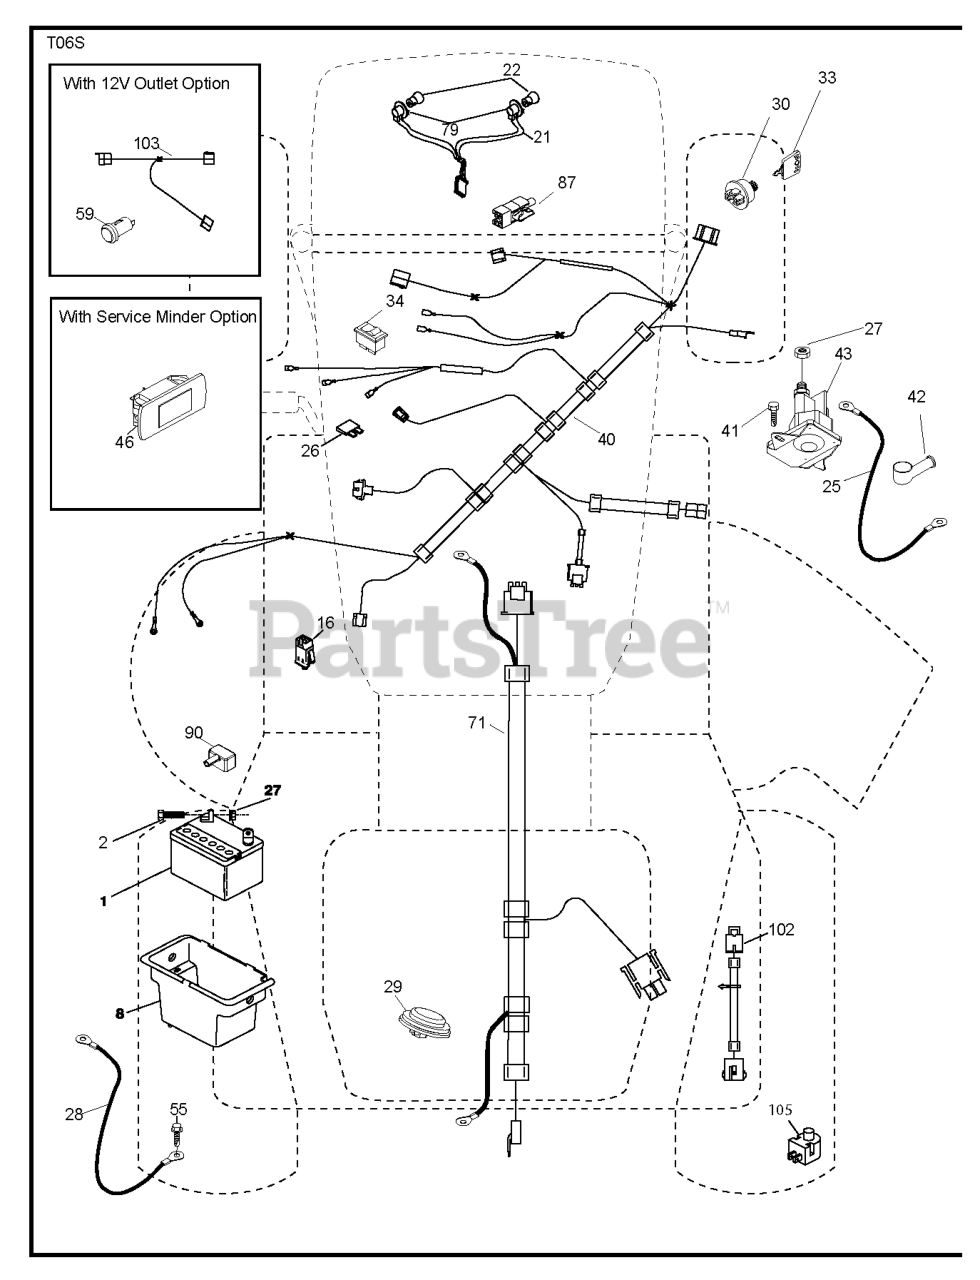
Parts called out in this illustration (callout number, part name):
1	Battery 12 Volt 25 Amp
2	BOLT.HEX.1/4.X.3/4.DICHROMATE
8	BOX.BATTERY.MNT.REAR.L
16	SWITCH INTERLOOK PUSH-IN
21	HARNESS.LIGHT W/4152J BULBS
25	CABLE.STARTER.6GA.BL/RED.14.
26	FUSE 20AMP
27	NUT
28	CABLE.BLACK.18"REAR.BA
29	SWITCH.SEAT.DELTA.OPC.
30	SWITCH.IGN.DELTA.W.LGH.ROS
33	KEY.CHAIN.BLISTER.PACK.GEN.USA
40	HARNESS IGN. DASH
41	SCREW
42	TERMINAL COVER
43	SOLENOID.W/BRASS.PLUNGER
46	RP.GUAGE.SRVCMNDR.HRMTR.
55	SCREW 5/16"
71	HARNESS.IGN.CHASS.TEX.REAR.BAT
79	BULB HOLDER ASM.
87	SWITCH.INTRLCK.CLUTCH.
90	COVER, TERMINAL BATTERY
102	HARNESS PIGTAIL PCH TEX ROS
105	REVERSE SWITCH
